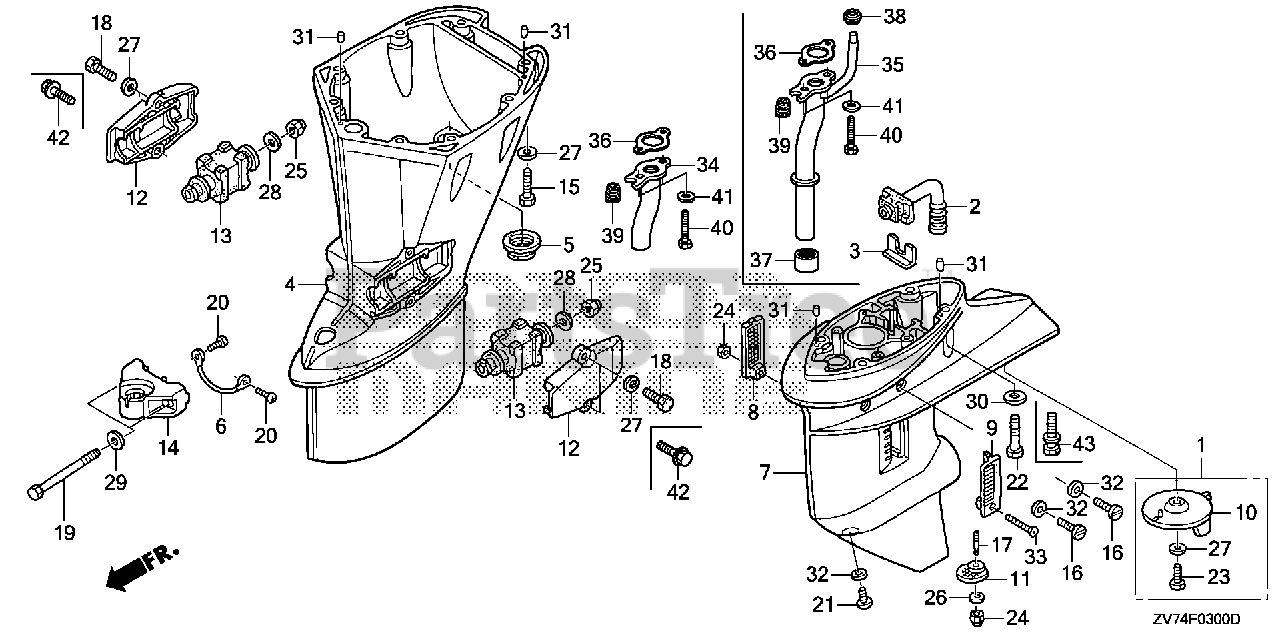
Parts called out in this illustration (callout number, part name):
1	TAB KIT, TRIM
2	TUBE, WATER (LOWER)
3	PLATE, RUBBER SETTING
4	CASE, EXTENSION *NH282MU* (S) (OYSTER SILVER METALLIC-U)
5	RUBBER, DRAIN PLUG
6	WIRE, LEAD (1.2X116MM)
6	WIRE, LEAD (1.5X116MM)
7	CASE, GEAR *NH282MU* (OYSTER SILVER METALLIC-U)
8	SCREEN, R. WATER
9	SCREEN, L. WATER
11	SCREEN, WATER (LOWER)
12	HOUSING, R. MOUNTING (LOWER) *NH282MU* (OYSTER SILVER METALLIC-U)
13	RUBBER, MOUNT (LOWER)
14	HOUSING, CENTER MOUNTING (LOWER) *NH282MU* (OYSTER SILVER METALLIC-U)
15	BOLT, HEX. (8X35)
16	BOLT, OIL CHECK
17	BOLT, STUD (5X12)
18	BOLT, HEX. (8X25)
19	BOLT, HEX. (12X162)
20	SCREW, PAN (6X8)
21	BOLT, DRAIN PLUG
22	BOLT, HEX. (10X40)
23	BOLT, HEX. (8X20)
24	NUT, SELF-LOCK (5MM)
25	NUT, SELF-LOCK (12MM)
26	WASHER, PLAIN (5MM)
27	WASHER, PLAIN (8MM)
28	WASHER, PLAIN (12MM)
29	WASHER, PLAIN (12MM)
30	WASHER, PLAIN (10MM)
31	PIN, DOWEL (6X10)
32	O-RING (5.5X1.5)
32	O-RING (6.9X1.45)
33	SCREW, OVAL (5X28)
36	GASKET, EX. PIPE
39	GROMMET, WATER TUBE
40	BOLT, HEX. (8X25)
41	WASHER, PLAIN (8MM)
